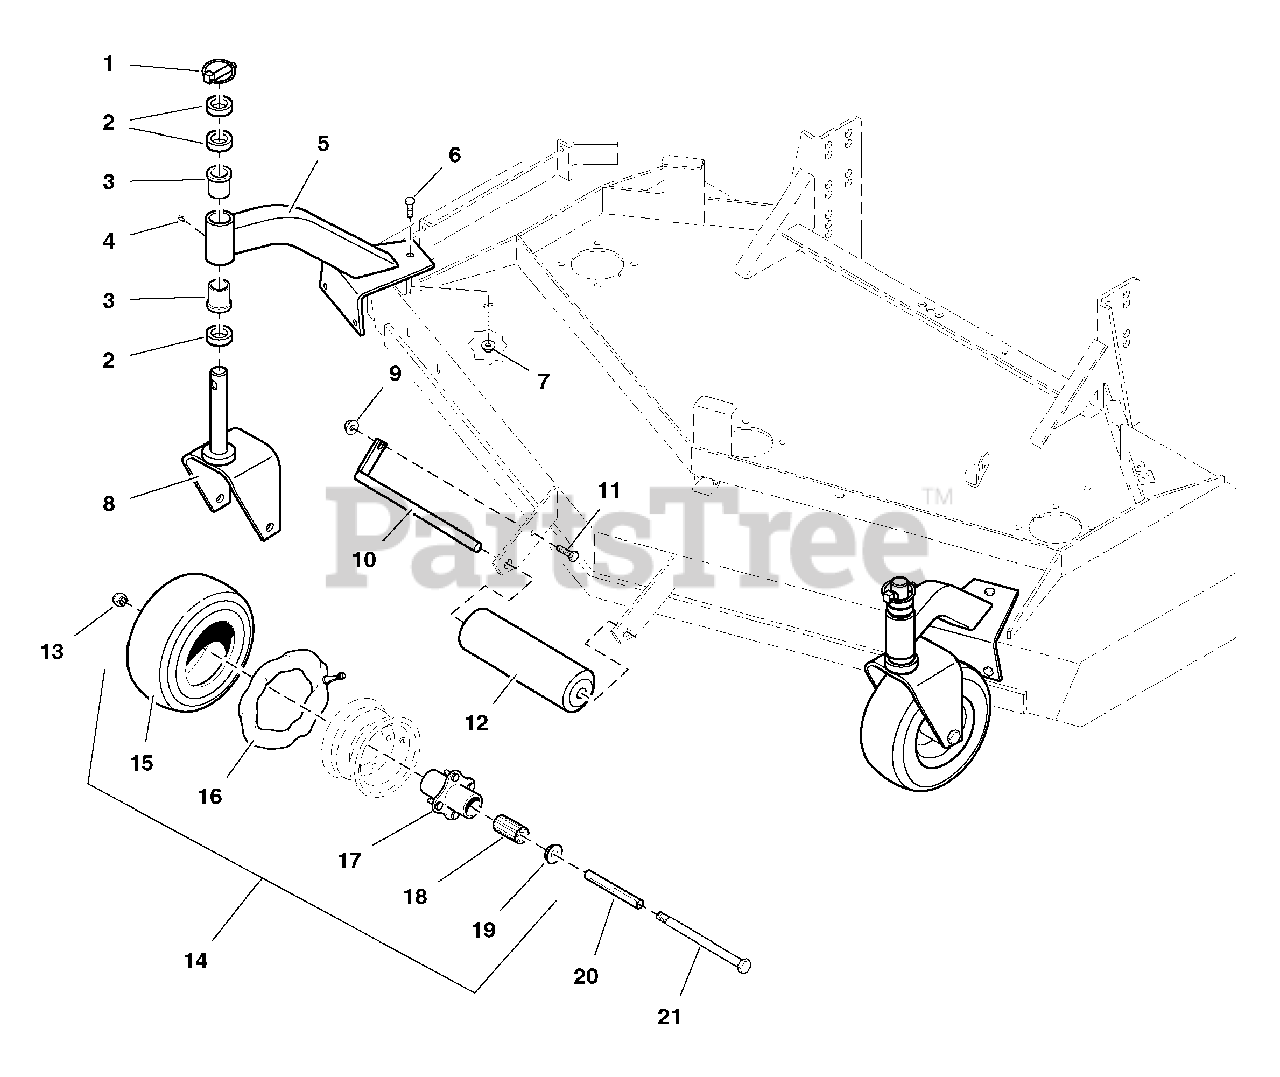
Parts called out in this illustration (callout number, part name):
2	CASTER SPACER
3	BUSHING, Flange
4	GREASE FITTING
5	CASTER MOUNT, Complete (includes Ref 3 & 4)
6	CAPSCREW, Hex Hd, 5/16-18 x 3/4
7	NUT, Hex, Serrated Flange, 5/16-18
8	CASTER YOKE
9	NUT, Hex, Serrated Flange, 3/8-16
10	WELD, BRACKET, ROLLER PIN - BLK
11	CAPSCREW, Hex Hd, 3/8-16 x 3/4
13	NUT, Hex, Nylon Lock, 1/2-13
14	WHEEL & TIRE ASSEMBLY, Front, Silver, 9 x 3.5 x 4, Complete (includes Ref 15 - 19)
15	TIRE, Front, 9 x 3.5 x 4
16	TUBE, for 9 x 3.5 x 4 Tire
17	HUB & BEARING ASSEMBLY, Complete, Silver (includes Ref 18 & 19)
18	BEARING, Roller (1 per tire)
19	RETAINER, Bearing (2 per tire)
20	AXLE, Caster
21	CAPSCREW, Hex Hd, 1/2-13 x 5-1/2
